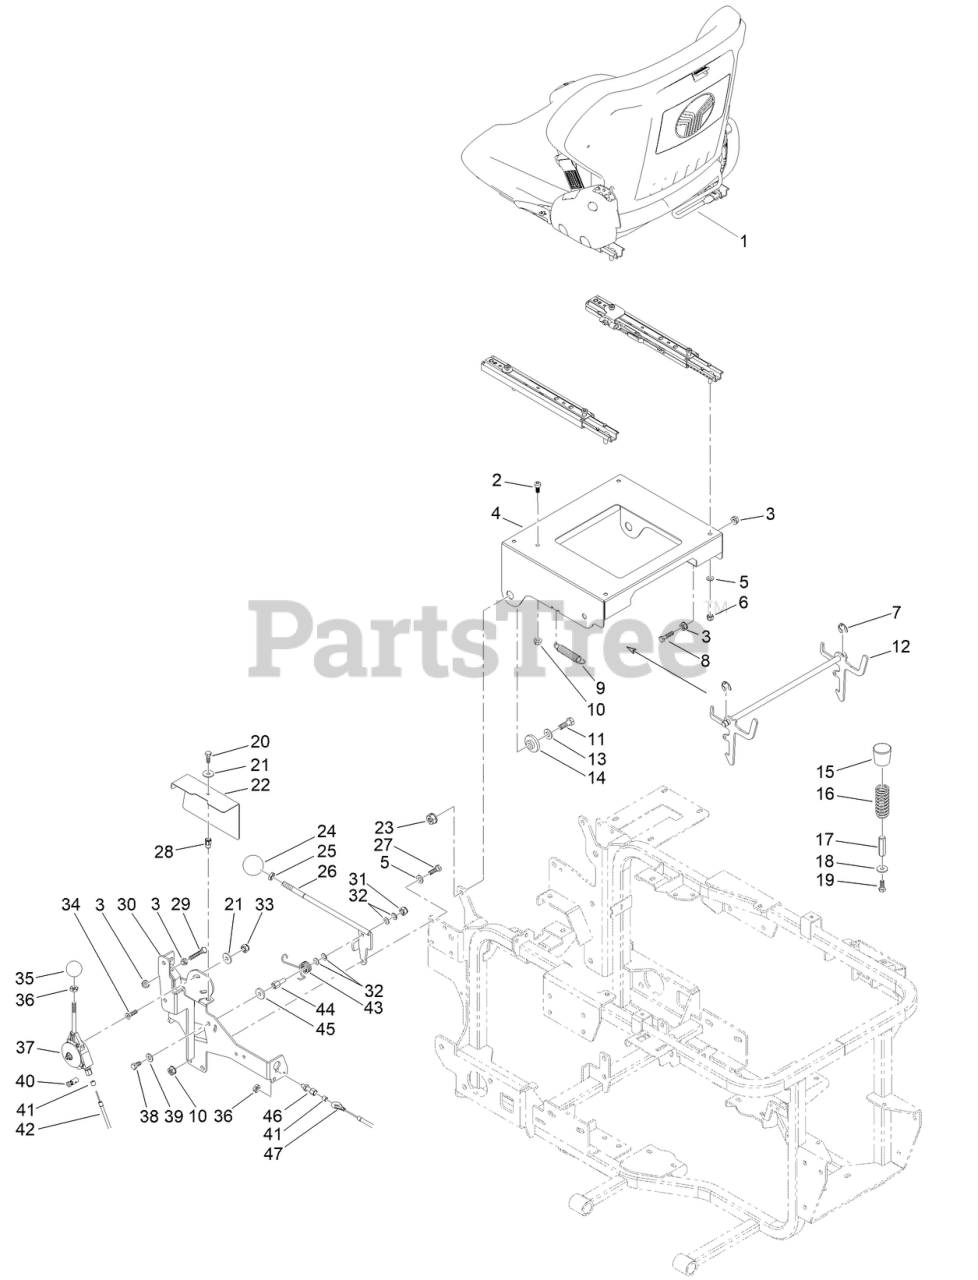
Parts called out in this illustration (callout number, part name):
1	SEAT, S421
4	SUPPORT, SEAT
5	WASHER
7	RING-SNAP
9	SPRING
12	HOOK, SEAT
13	WASHER
14	BUSHING
15	PLUG, RUBBER
16	SPRING-COMPRESSION
17	COLUMN - HEX
18	WASHER
21	WASHER
22	COVER, PARKING BRAKE LEVER
24	BALL, THREADED INSERT M10
26	HANDLE, PARKING BRAKE
28	INSERT-THREADED
29	SCREW, H-SCKT CSK
30	SUPPORT, TRHOTTLE/PARKING BRAKE DEVICES
32	WASHER, BELLEVILLE
37	LEVER-THROTTLE
39	WASHER
40	CABLE-CLAMP
41	CABLE-END, NIPPLE
42	CABLE, THROTTLE
43	SPRING, PARKING BRAKE HANDLE
44	PIVOT, PARKING BRAKE HANDLE
45	WASHER-PLAIN
46	REGISTER
47	CABLE, PARKING-BRAKE
